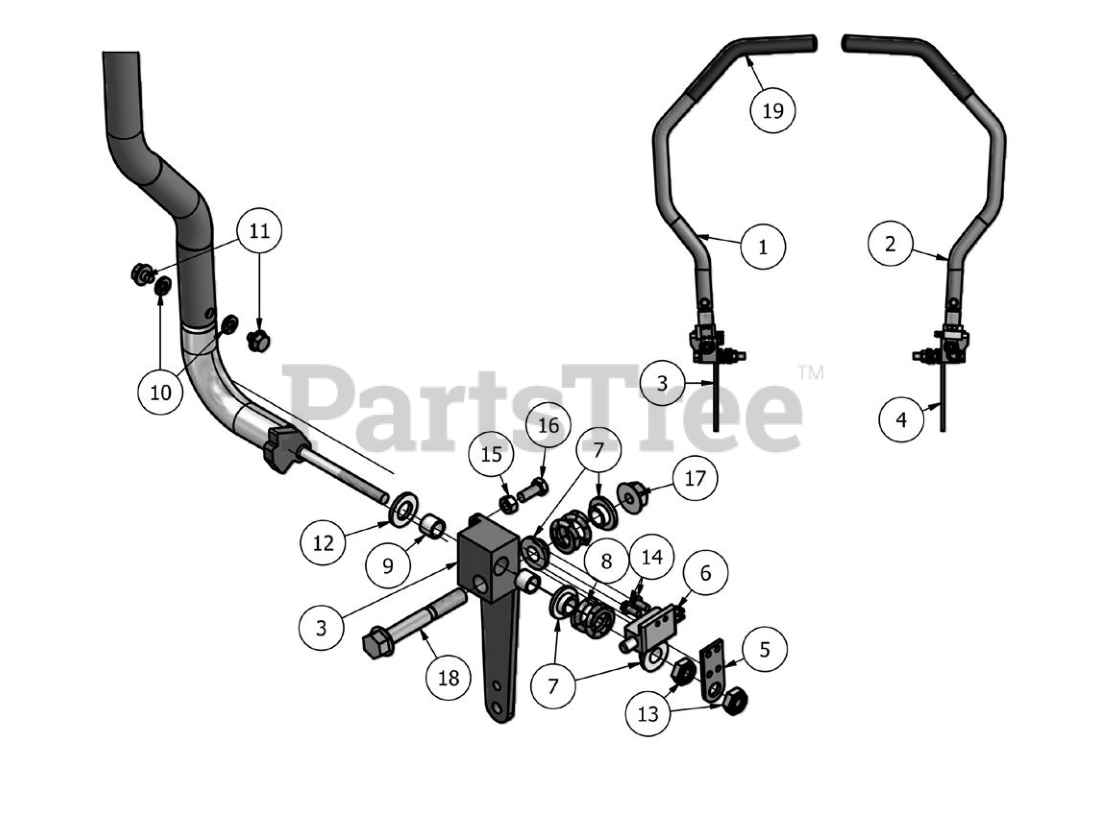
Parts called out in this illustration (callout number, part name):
1	ZT Direction Steering Arm (Left)
2	Direction Steering Arm (Right)
3	Drive Arm Lever Housing (Left)
4	Drive Arm Lever Housing (Right)
5	MZ Switch Bracket
6	Safety Switch
7	.515 ID Nylon Shoulder Washer
8	Drive Lever Spring
9	.507 ID Nylon Bushing
10	5/16" Lock Washer
11	5/16" x 1/2" Flange Bolt
12	.635 ID Plastic Washer
13	1/2-20 Nylon Insert Jam Locknut Zinc Orange Zinc
14	12-24 x 1/2 Hex Washer Head bolt
15	5/16-18 Hex Nuts Zinc
16	5/16-18 x 3/4 Grade 5 Hex bolt Zinc
17	1/2-13 Nylon Insert Flangenut Zinc Orange Nylon
18	1/2 x 3-1/2 Flange Bolt - Grade 8
19	Rubber Steering Arm
